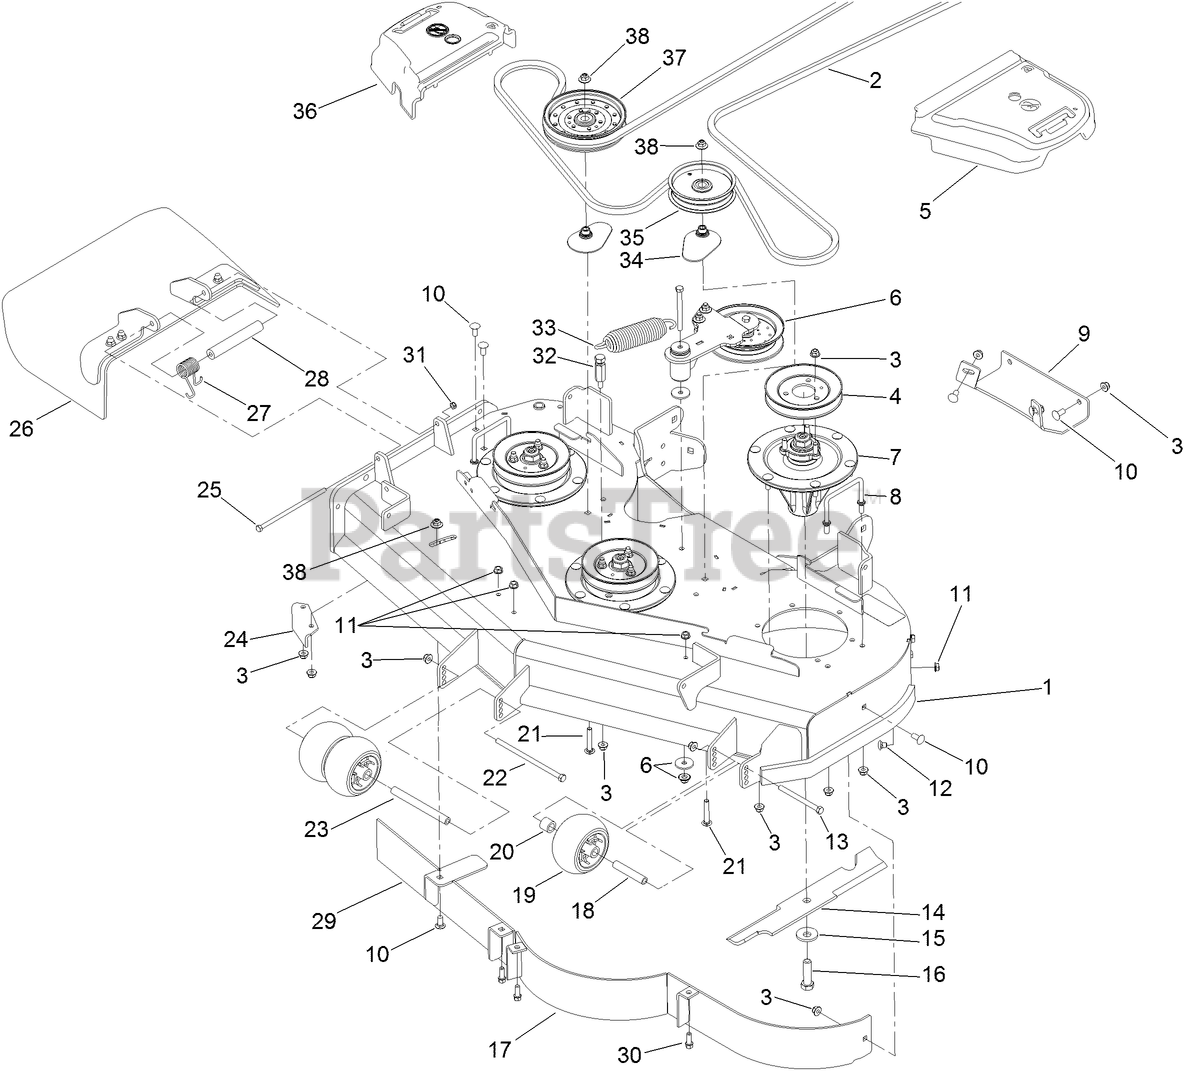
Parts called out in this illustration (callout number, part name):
1	DECK DECAL ASM
2	BELT-V
3	NUT-HF, NI
4	PULLEY
5	COVER-BELT, LH
6	IDLER ARM ASM
7	SPINDLE ASM
8	WIREFORM-COVER
9	PLATE-SKID
10	SCREW-CARR
11	NUT-HHF, WHIZ
12	SCREW-CARR
13	SCREW-HH
14	BLADE-16.5 INCH (HIGH FLOW)
15	Washer-Blade Bolt, Heavy
16	SCREW-BLADE
18	TUBE-SPANNER
19	ROLLER-SCALP, ANTI
20	TUBE-SPACER
21	BOLT-CARR, SHORT NECK
22	SCREW-HH
23	SPACER-WHEEL
24	BAFFLE-DISCHARGE
25	SCREW-HH
26	RUBBER DEFLECTOR ASM
27	SPRING-TORSION
28	SPACER
29	BAFFLE ASM
30	SCREW-HWH
31	NUT-LOCK, NI
32	ANCHOR-SPRING, TALL
33	SPRING-EXTENSION
34	SPACER-PULLEY
35	PULLEY-IDLER, FLAT
36	COVER-BELT, RH
37	PULLEY-IDLER, FLAT
38	NUT-FLANGE, NI
